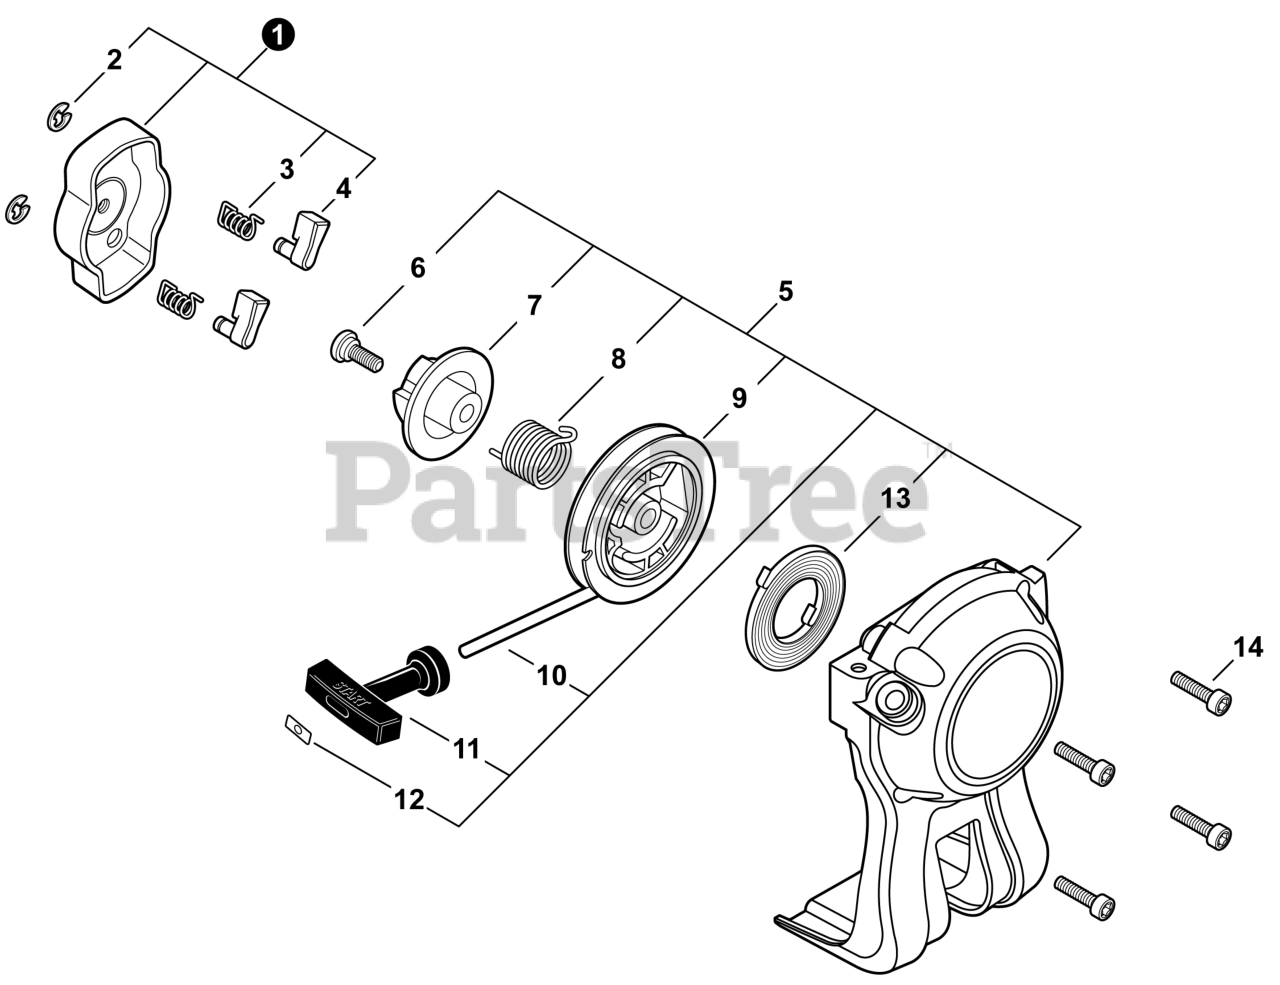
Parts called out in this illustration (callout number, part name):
1	PAWL ASSY, STARTER
2	E-RING 4
3	SPRING, RETURN
4	PAWL, STARTER
5	STARTER ASSY, RECOIL
6	SCREW 5
7	PLATE, CAM
8	SPRING, TORSION
9	REEL, ROPE
10	ROPE, STARTER 3x700
11	GRIP, STARTER
12	RETAINER, ROPE
13	SPRING, RECOIL
14	BOLT, TORX 4x16
